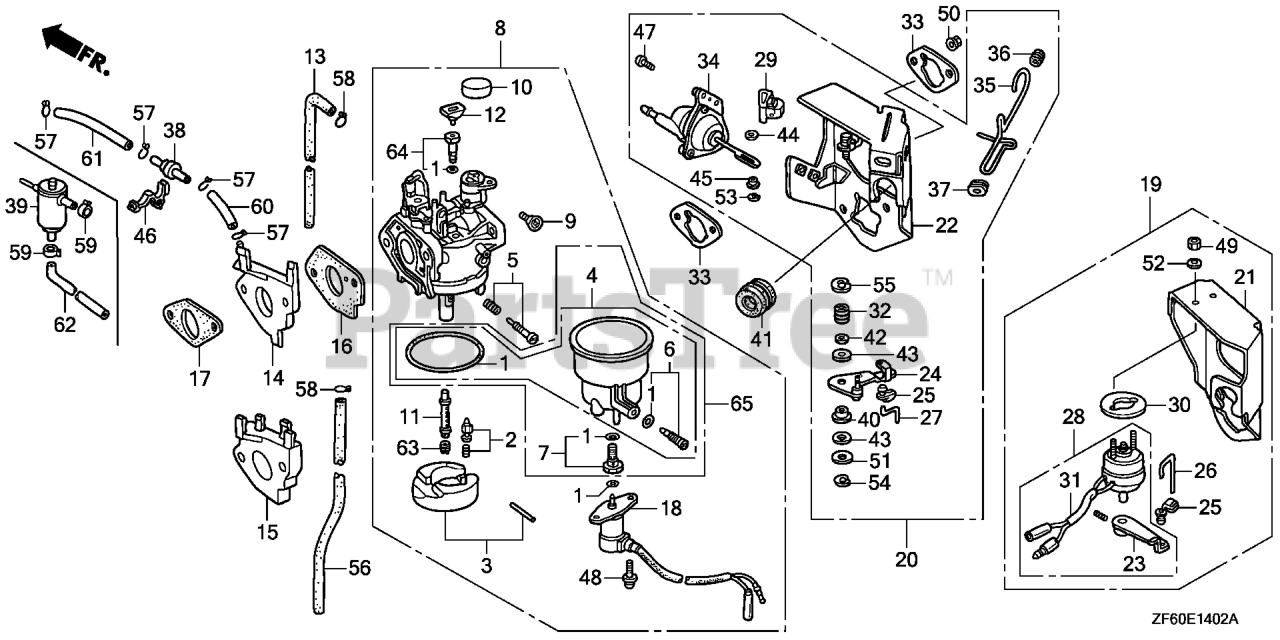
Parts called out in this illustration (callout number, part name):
1	GASKET SET
2	VALVE SET, FLOAT
3	FLOAT SET
4	CHAMBER SET, FLOAT
5	SCREW SET
6	SCREW SET, DRAIN (ADVENTURE GREEN) (CARBURETOR NO.)
7	SCREW SET B
8	CARBURETOR ASSY. (BE87A C)
9	SCREW, THROTTLE STOP
10	CAP, CHOKE LEVER DUST
11	NOZZLE, MAIN
12	COLLAR, SET
15	INSULATOR, CARBURETOR
16	GASKET, CARBURETOR
17	GASKET, INSULATOR Use up to Engine SN 2949254.
18	VALVE ASSY., SOLENOID
20	STAY ASSY., MANUAL CHOKE
22	STAY, SOLENOID
24	LEVER, CHOKE
25	JOINT, ROD
27	ROD, CHOKE
29	STOPPER, CHOKE ROD
32	SPRING, MANUAL CHOKE
33	GASKET, AIR CLEANER
34	DIAPHRAGM ASSY.
35	ROD, CHOKE CONTROL
36	GROMMET, CHOKE ROD
37	GUIDE, CHOKE ROD
38	VALVE, DASHPOT CHECK
40	BUSH, ARM PIVOT
41	GROMMET, FENDER
42	WASHER, CHOKE LEVER
43	SEAL, CHOKE LEVER
44	WASHER, THRUST (2.7X8)
45	COLLAR, LEVER
46	CLIP, WIRE HARNESS
47	SCREW, PAN (5X12)
48	SCREW-WASHER (5X12)
50	NUT, FLANGE (6MM)
51	WASHER, PLAIN (5MM)
53	E-RING (2MM)
54	E-RING (4MM)
55	E-RING (7MM)
57	CLIP, TUBE (B7)
60	BULK HOSE, VACUUM (3.5X8000) (3.5X130)
61	BULK HOSE, VACUUM (3.5X8000) (3.5X130)
63	JET, MAIN (#98) Use from Engine SN BE87A A to BE87A A.
63	JET, MAIN (#100) Use from Engine SN BE87A A to BE87A A.
63	JET, MAIN (#102) (ADVENTURE GREEN) (CARBURETOR NO.)
64	JET SET, PILOT (#45)
